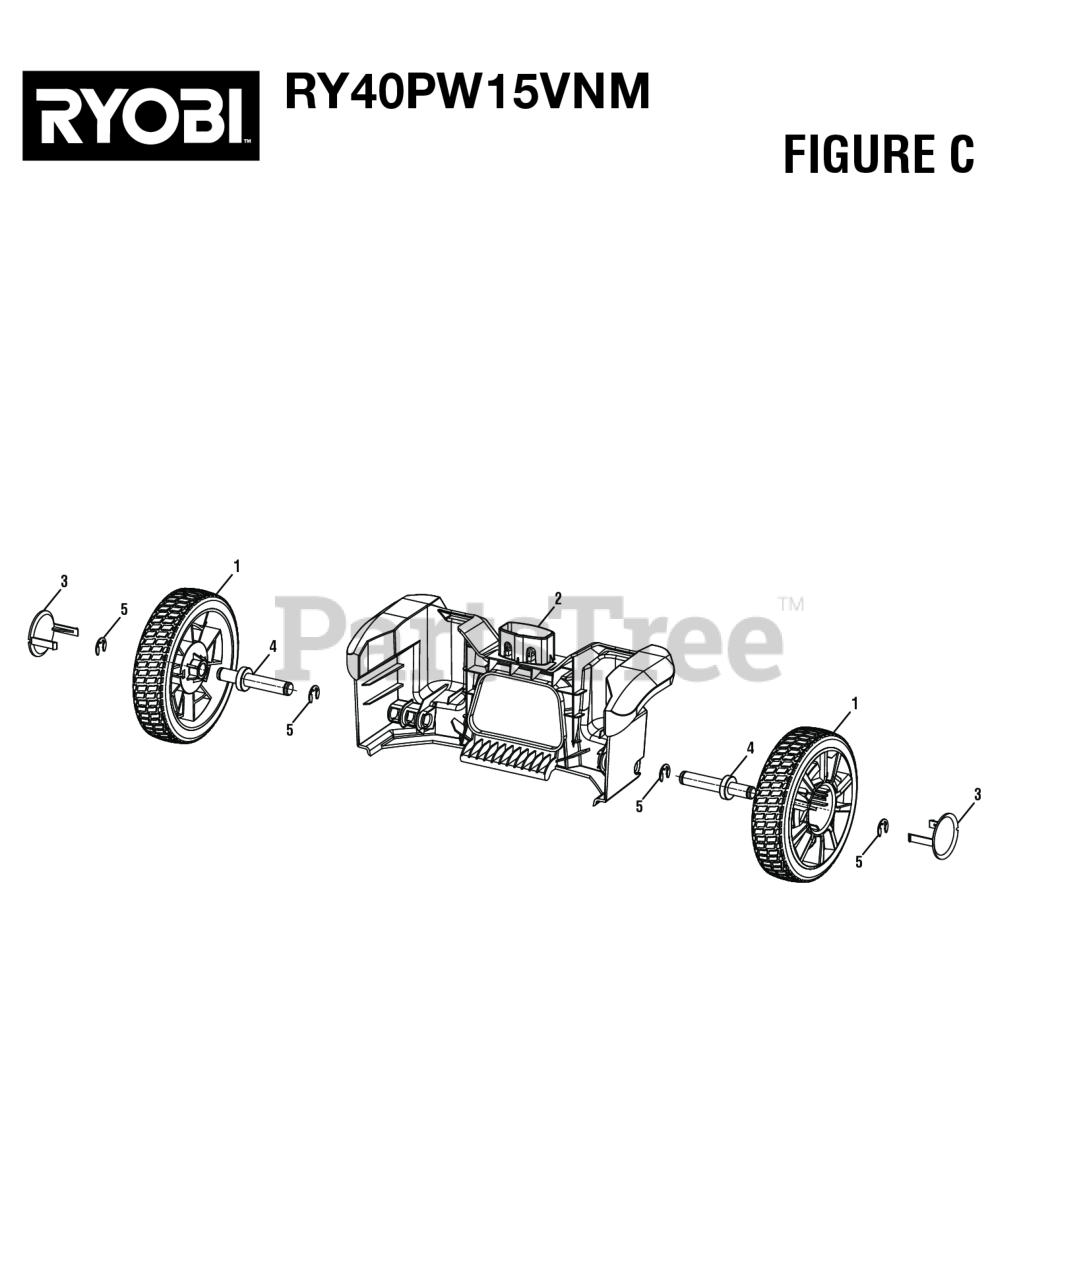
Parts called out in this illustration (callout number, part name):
2	Wheel Base Bracket
3	Wheel Cover
4	Wheel Axle
5	Retaining Ring
